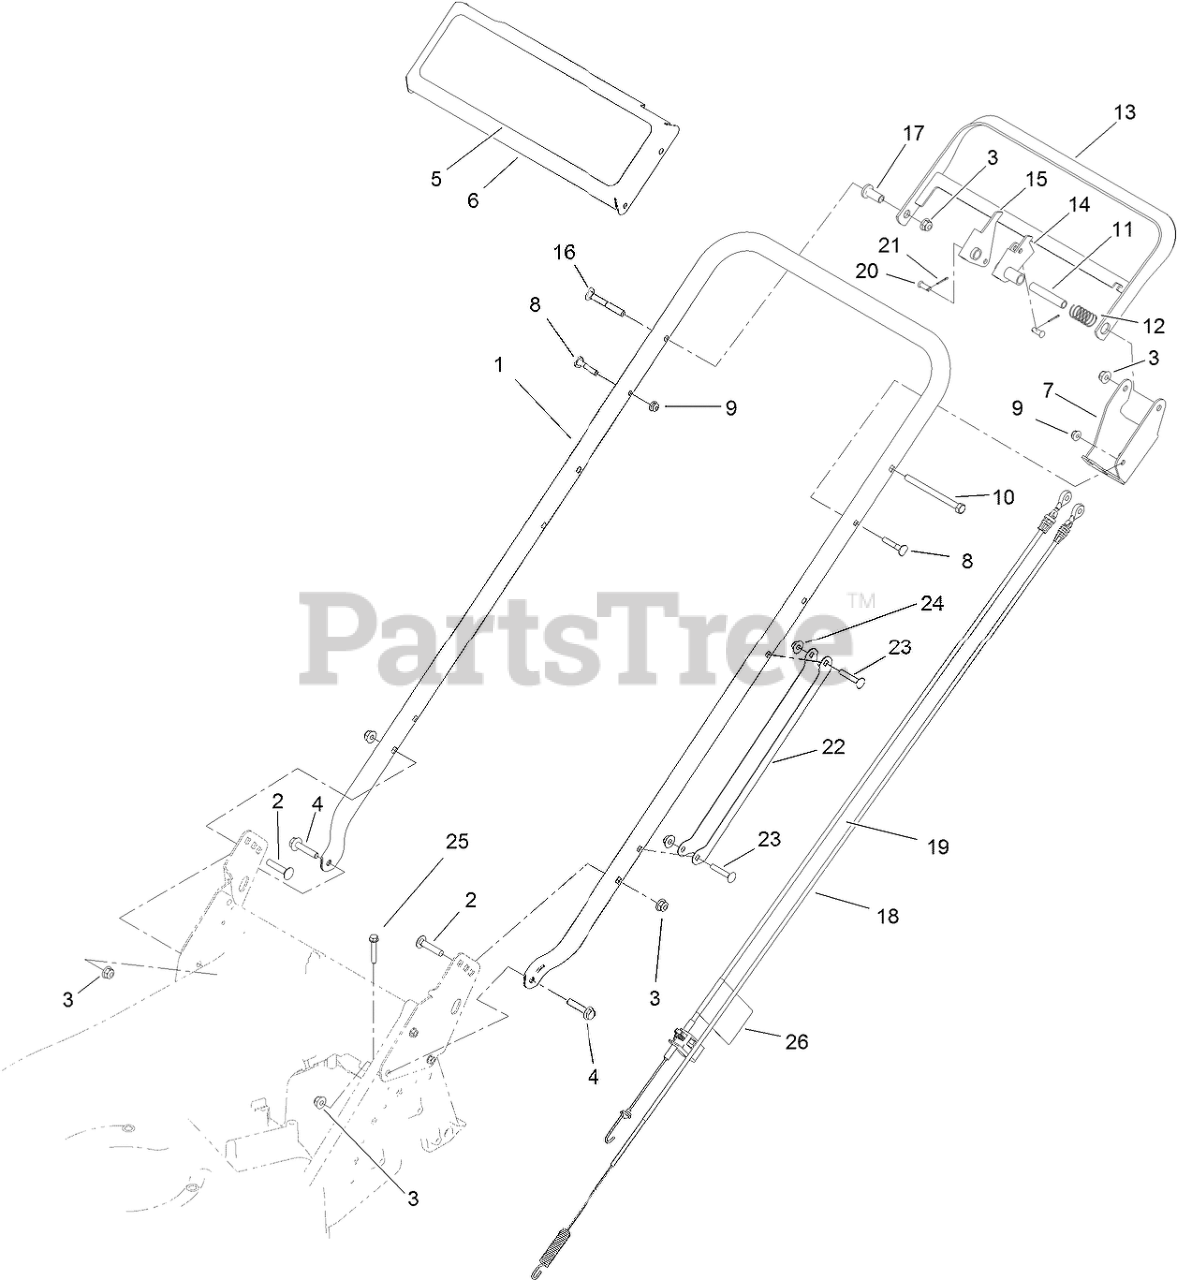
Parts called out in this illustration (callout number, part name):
1	HANDLE
2	BOLT-CARR
3	NUT-HF, NI
4	SCREW-HHF
5	DECAL-TORO, COMMERCIAL
6	PANEL-CONTROL
7	BRACKET-CONTROL
8	SCREW-HANDLE
9	NUT-HF
10	SCREW-HH
11	SPACER
12	SPRING-CONTROL
13	BAR-CONTROL
14	LEVER-CONTROL
15	LEVER-TRACTION
16	SCREW-HANDLE
17	SPACER-FLANGE
18	CABLE-BBC
19	CABLE-TRACTION, BBC
20	PIN-CABLE
21	PIN-COTTER
22	GUARD-CABLE, HANDLE
23	SCREW-CARR
24	NUT-HEX FLG
25	SCREW-HWH
26	DECAL-ADJUST, SELF PROPEL DRIVE
